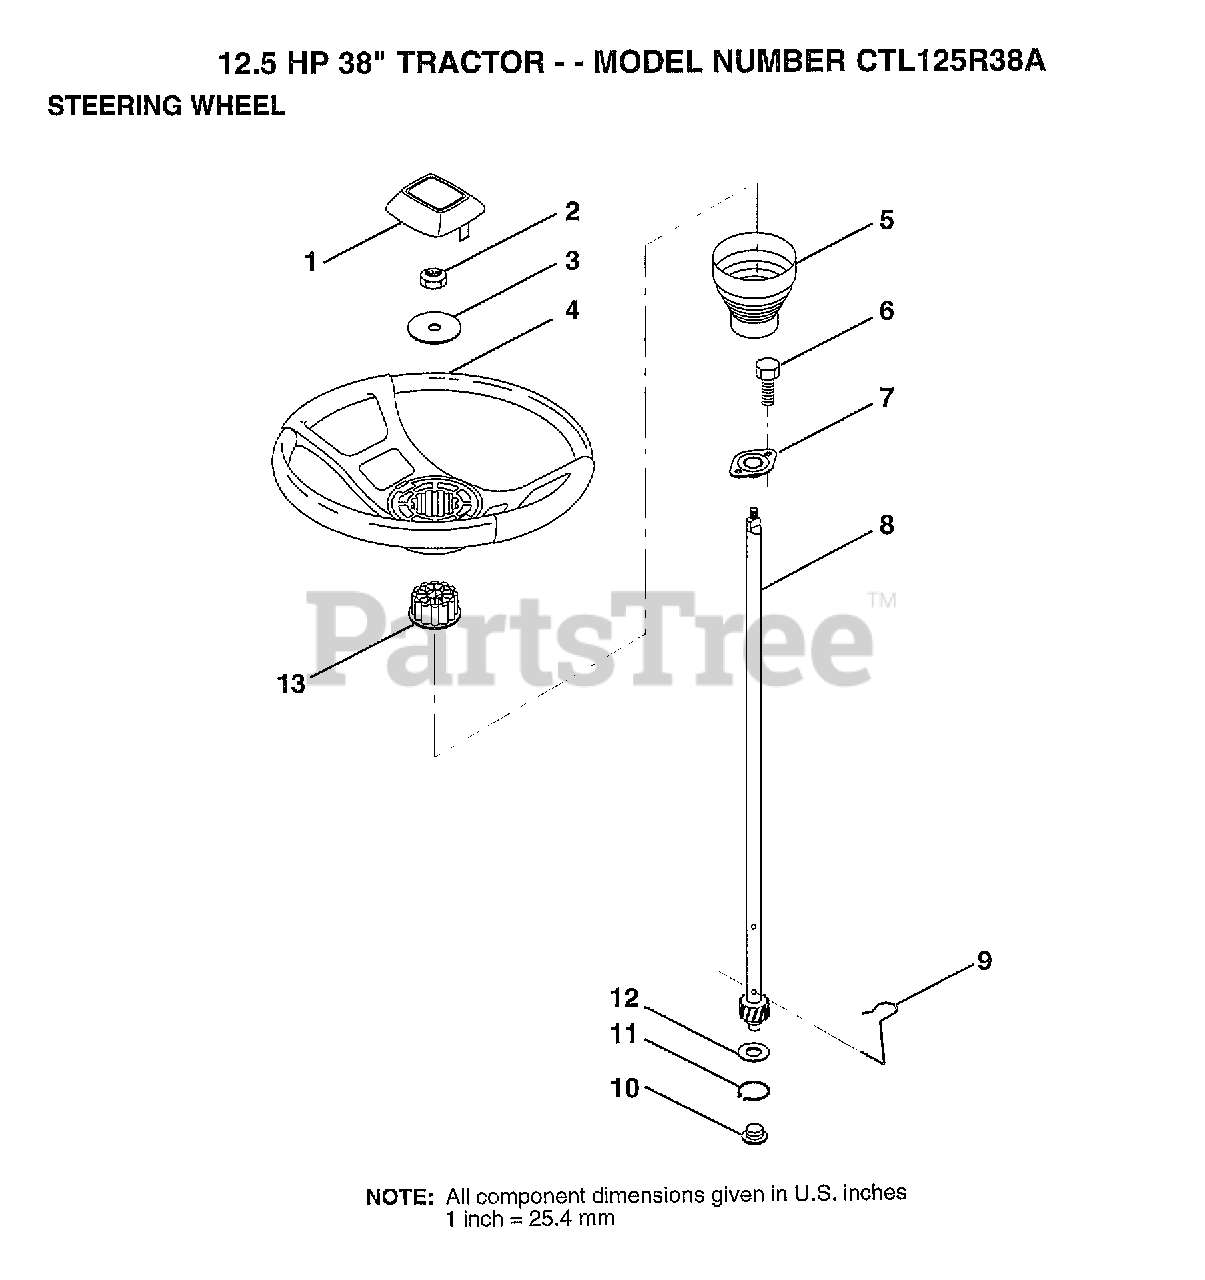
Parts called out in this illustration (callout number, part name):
1	ST WHL INSERT CAP
2	GRIPCO NUT
3	WASHER T
5	SLEEVE STEERING
9	STEERING CLIP
10	BUSHING STEER LWR
11	RING
12	WASHER LT
13	ADAPTER-WHEEL LT
